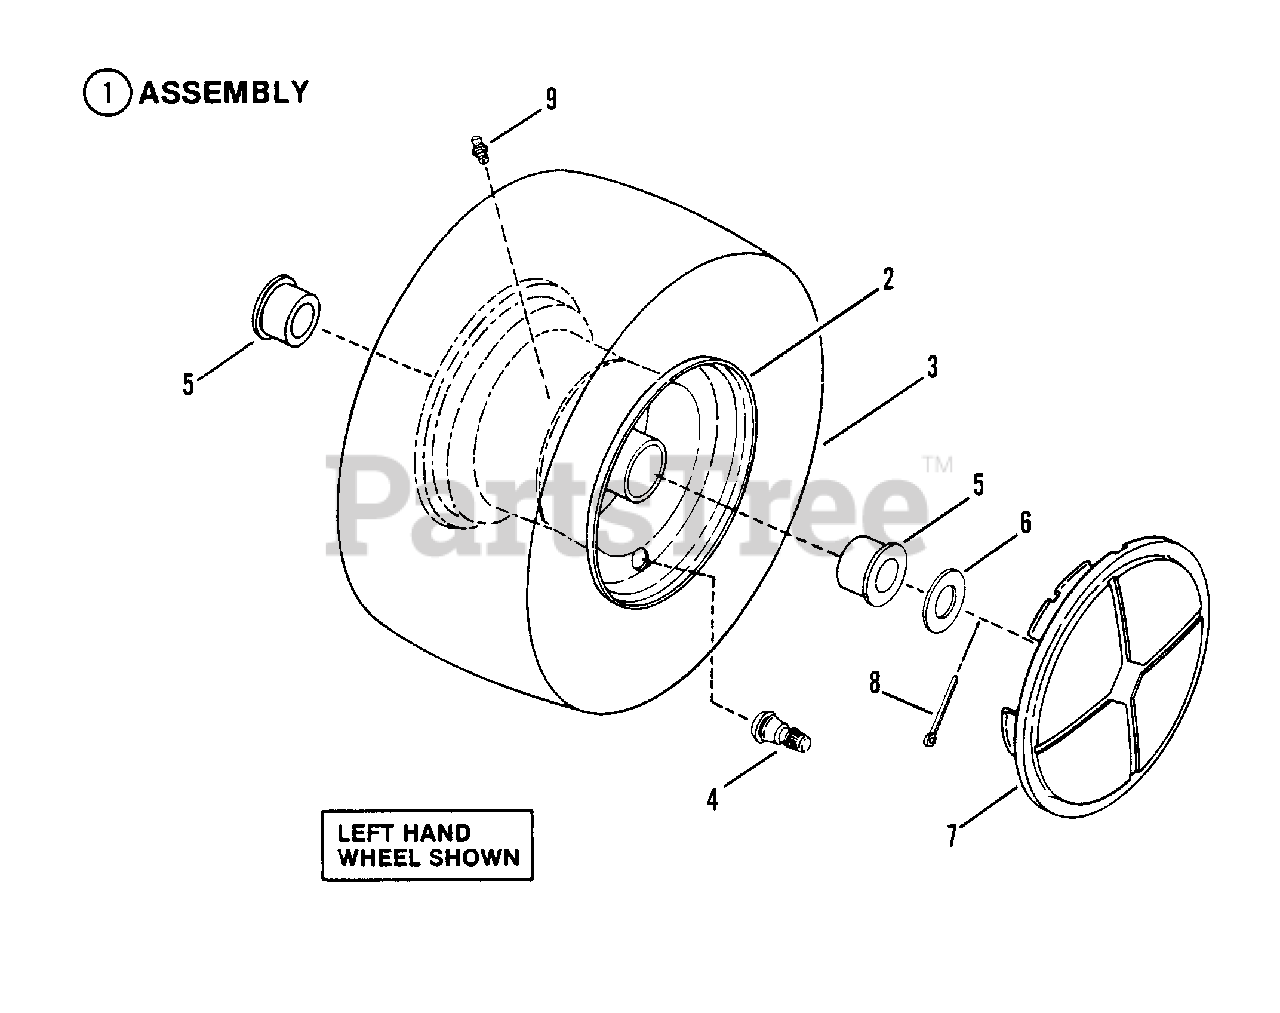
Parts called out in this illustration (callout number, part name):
1	ASSEMBLY, Front Tire & Rim 15x5.50-6.00
2	RIM, 6 x 4.50
3	TIRE, 15-6.00 x 6
4	VALVE, Air (Snap-in)
5	BEARING, Wheel Flanged PM .758 ID x 1.38 OD x 1.0 L
6	WASHER .77 x 1.5 x .06
7	WHEEL-COVER
8	COTTER-PIN 5/32 x 1 YZ
9	FITTING, Lube 1/4-28 Tapered Thread
